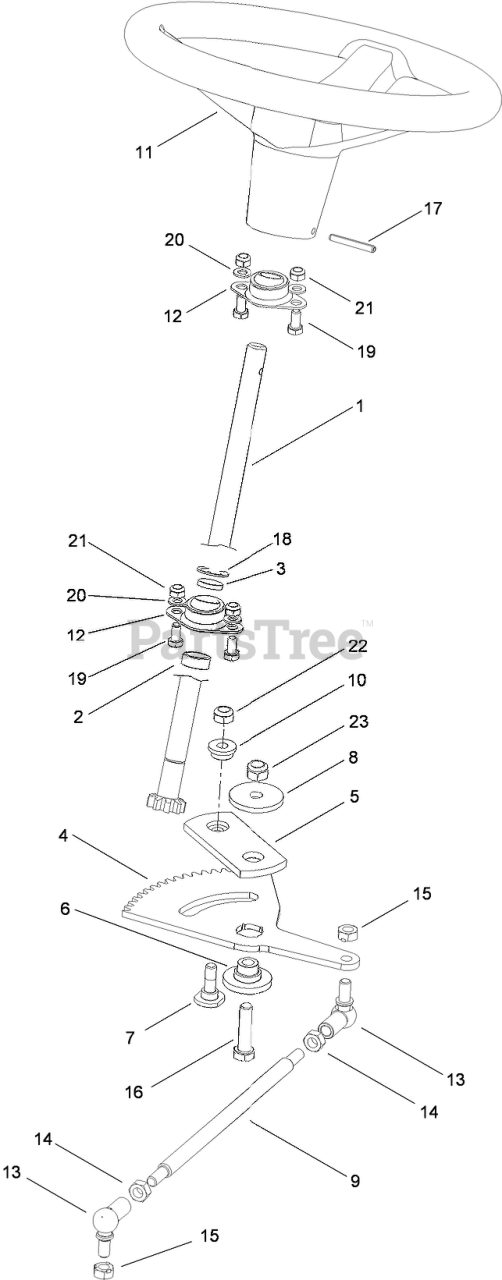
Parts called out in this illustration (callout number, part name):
1	SHAFT-STEERING
2	SPACER-LOWER
3	SPACER-UPPER
4	GEAR-SECTOR
5	Plate-Steering
6	Pivot-Steering
7	Bolt-Shoulder
8	WASHER
9	LINK-DRAG
10	Bushing
11	WHEEL-STEERING
12	BEARING-SPHERICAL
13	JOINT-BALL, ANGLE
14	NUT-HEX
15	NUT-LOCK, NI
16	SCREW-HH
17	PIN-SPIROL
18	CLIP-SPRING
19	SCREW-HH
20	WASHER-PLAIN
21	NUT-LOCK, NI
22	NUT-LOCK
23	NUT-HEX
